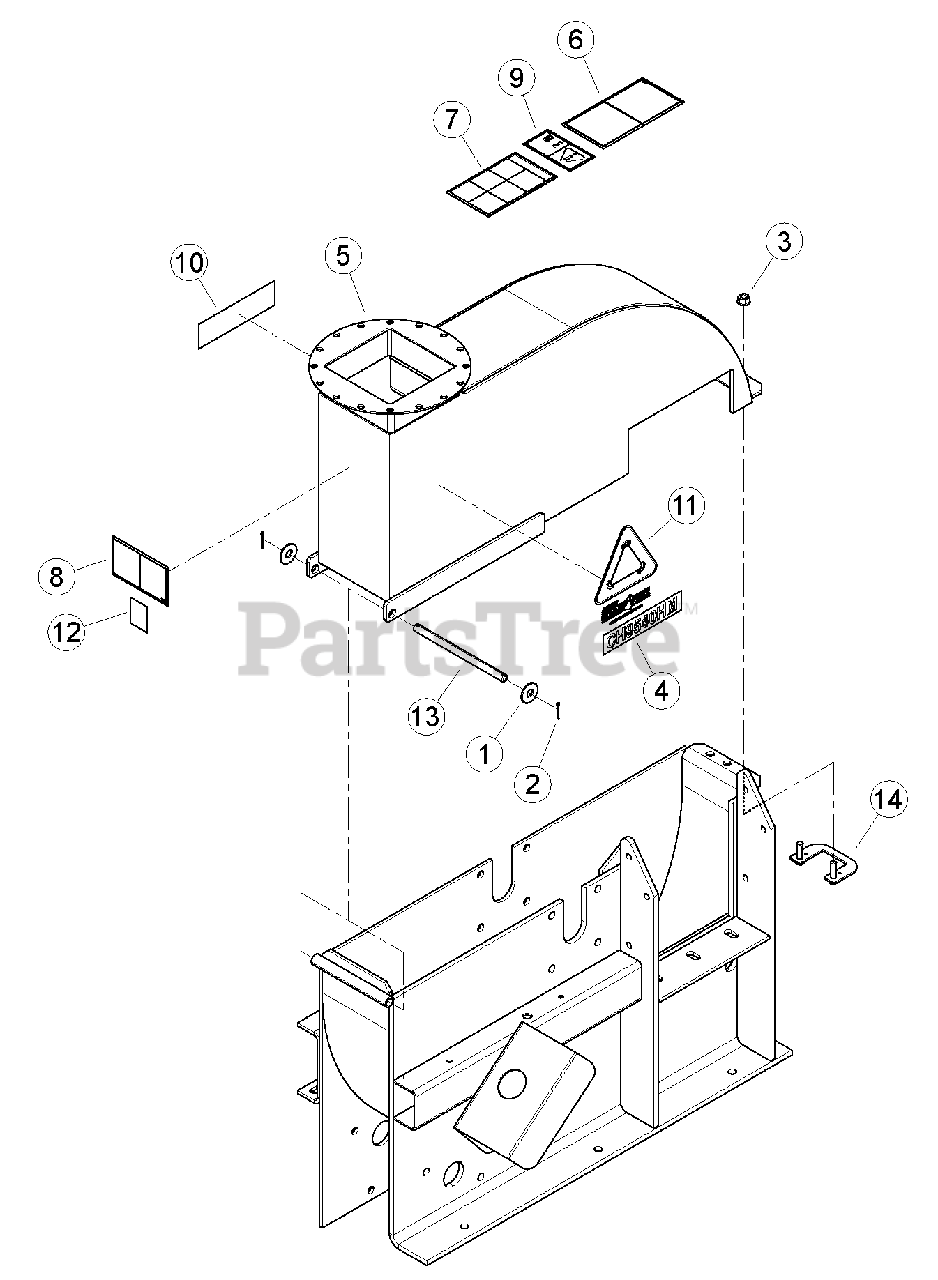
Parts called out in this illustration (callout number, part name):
1	WASHER, 1/2 FLAT
2	PIN, 1/8 X 1.00 ZP COTTER
3	NUT, 3/8-16 NYLOCK FLANGE
4	DECAL, MODEL CH9540HM
5	ASSEMBLY, CHIPPER COVER W/ DECALS
6	DECAL, KNIFE ACCESS ISO
7	DECAL, OPERATING INSTRUCTIONS ISO
8	DECAL, DISCHARGE ISO
9	DECAL, MAINTENANCE ISO
10	DECAL, ECHO BEARCAT 6.82 X 1.90
11	DECAL, CHIP IT
12	DECAL, ECHO BEARCAT QR CODE
13	SHAFT, CHIPPER TOP PIVOT
14	WELDMENT, CHIPPER HOUSING ACCESS
